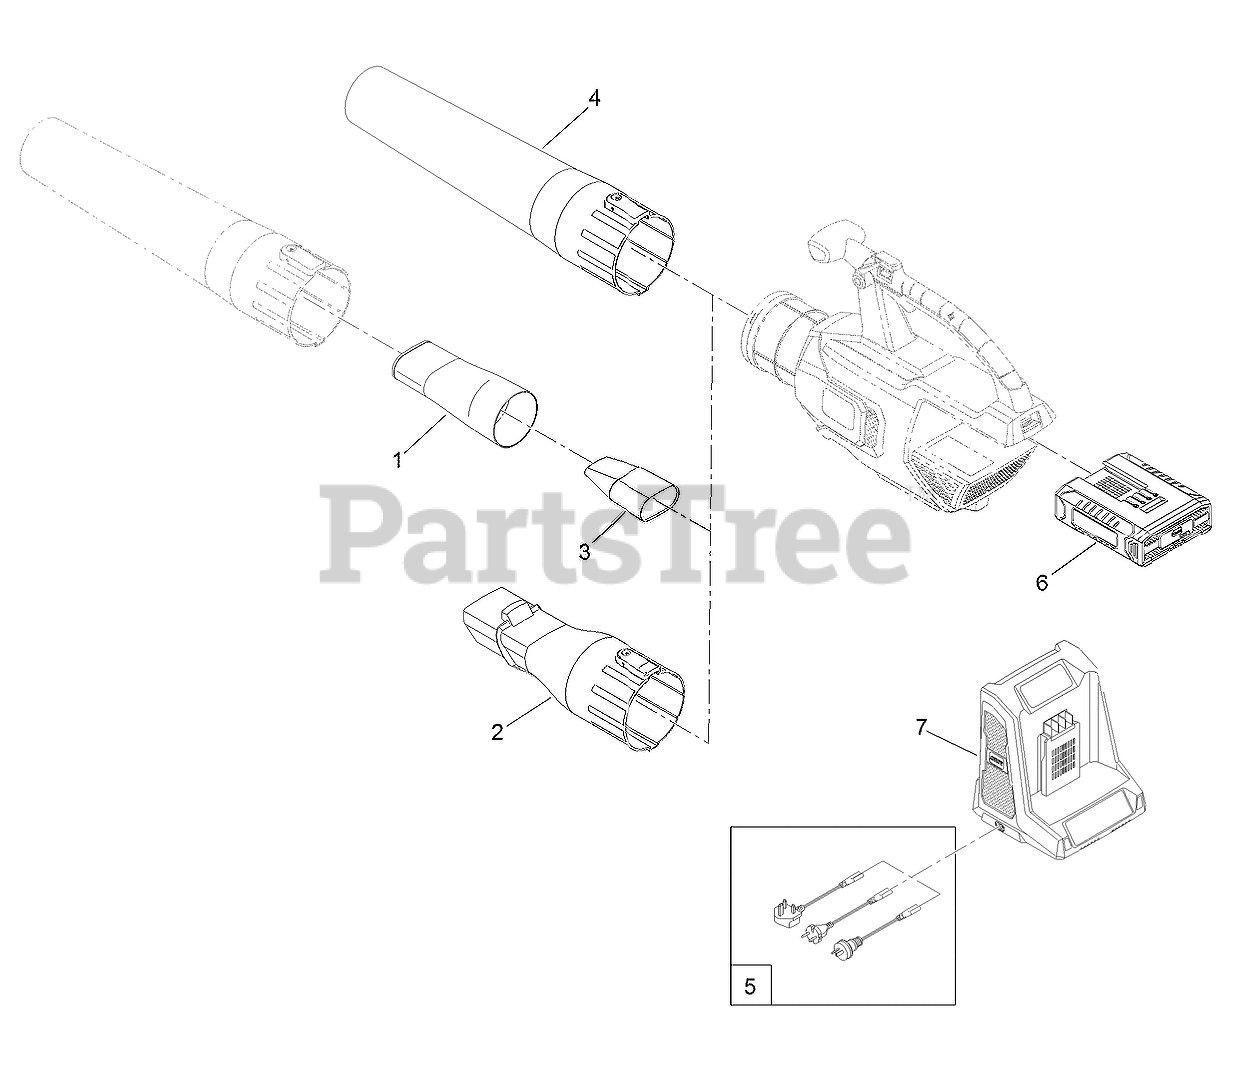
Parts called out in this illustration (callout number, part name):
1	ADAPTER-OSCILLATOR, MPH
2	ADAPTER-CLEANER, GUTTER
3	ADAPTER-INSERT, MPH
4	TUBE-BLOWER
5	CORD SET
6	BATTERY-40V MAX
7	CHARGER-BATTERY, 40V MAX
